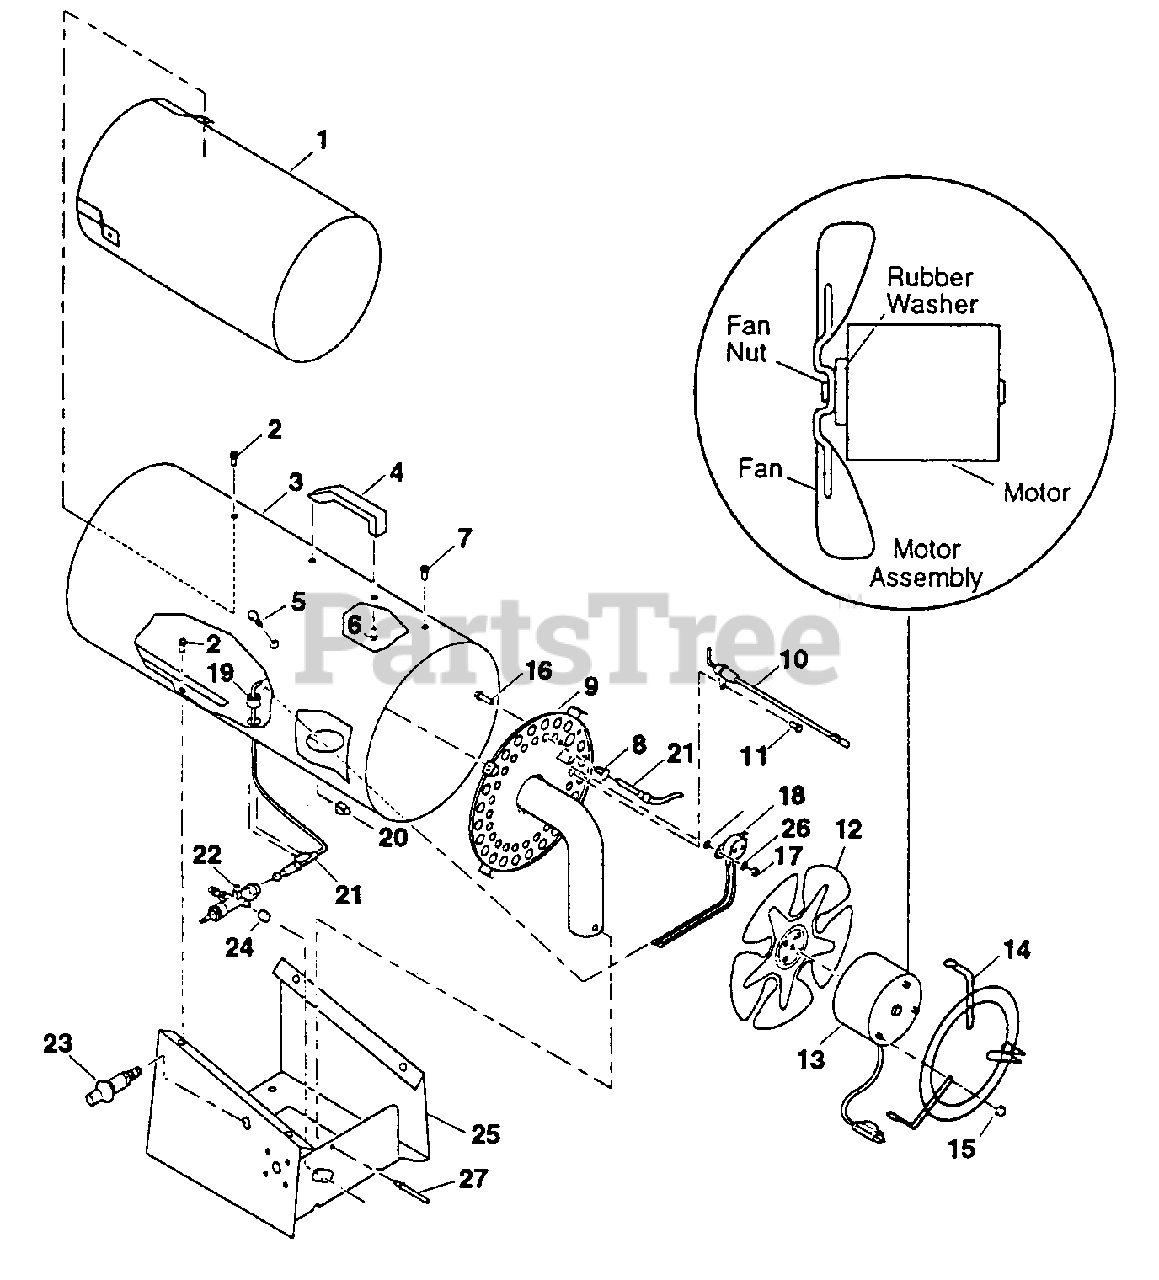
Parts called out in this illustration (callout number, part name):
1	INNER SHELL (Combustion Chamber)
2	SCREW-Hex Tap (#10-16 X 3/8")
3	OUTER SHELL
5	SCREW-Hex Tap Shoulder
6	SCREW-Hex Tap (#10-16 X 3/4")
7	SCREW-Hex Tap (#12-14 X 1/2")
8	THERMOCOUPLE CLIP
9	BURNER ASSEMBLY
10	ELECTRODE IGNITOR
11	SCREW-Hex Tap (#8- 1 8 X 3/8")
13	MOTOR ASSEMBLY
14	FAN GUARD
15	CAPTIVE WASHER NUT
16	SCREW-Hex (#4-40 X 1/4")
17	NUT-Hex (#4-40)
18	THERMAL SWITCH ASSEMBLY
19	UNIVERSAL BUSHING
20	WIRE CLIP
21	THERMOCOUPLE
22	VALVE/ORIFICE ASSEMBLY
23	PIEZO IGNITOR
24	SLEEVE CAP
26	WASHER-Lock (#4)
27	STEEL RIVET (1/8")
